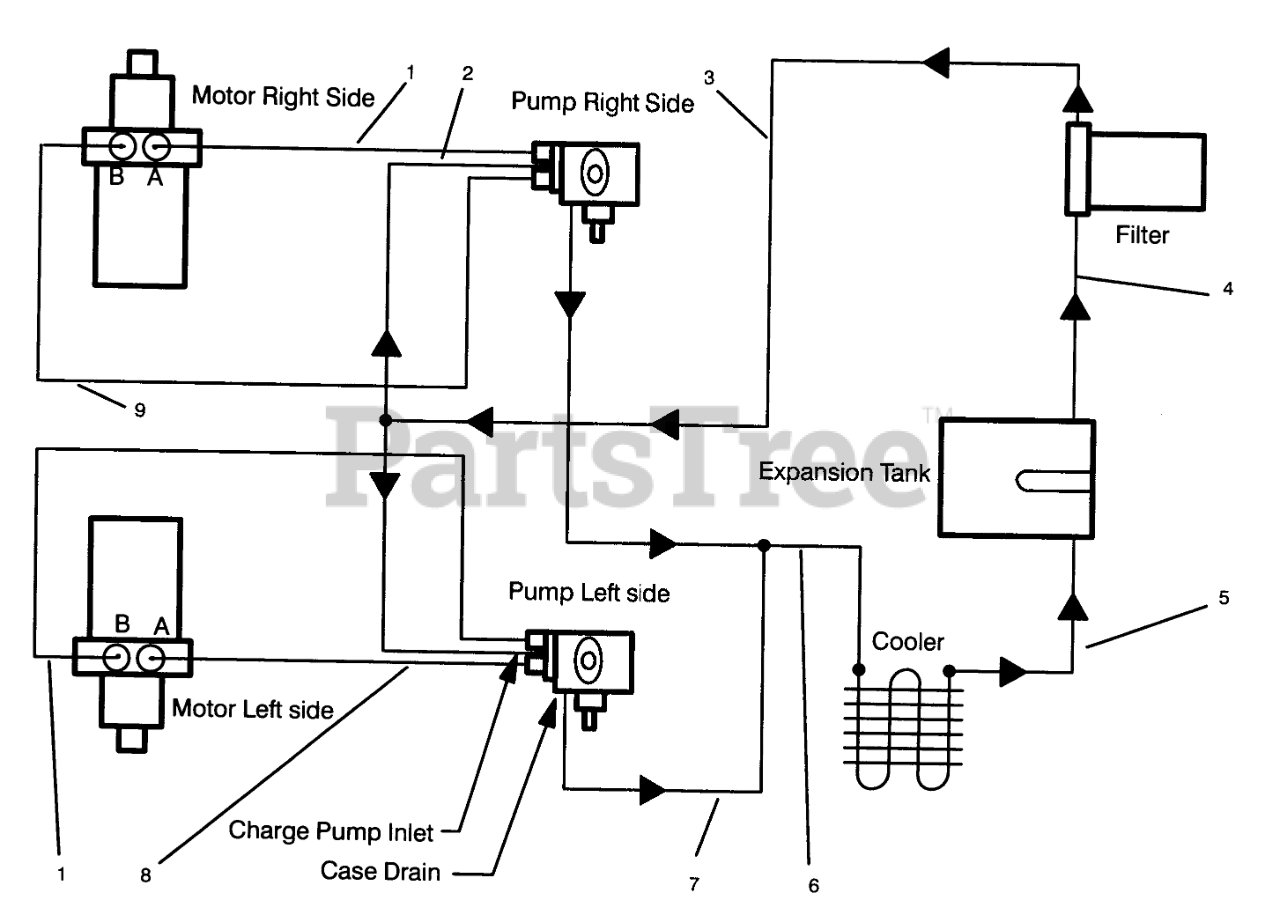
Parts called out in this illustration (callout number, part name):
1	HYDRAULIC HOSE ASM
2	HYD HOSE ASM
3	HYDRAULIC HOSE ASM
4	HYD HOSE ASM
5	HYDRAULIC HOSE ASM
6	HYDRAULIC HOSE ASM
7	HYD HOSE ASM
8	HYDRAULIC HOSE ASM
9	HYDRAULIC HOSE ASM
